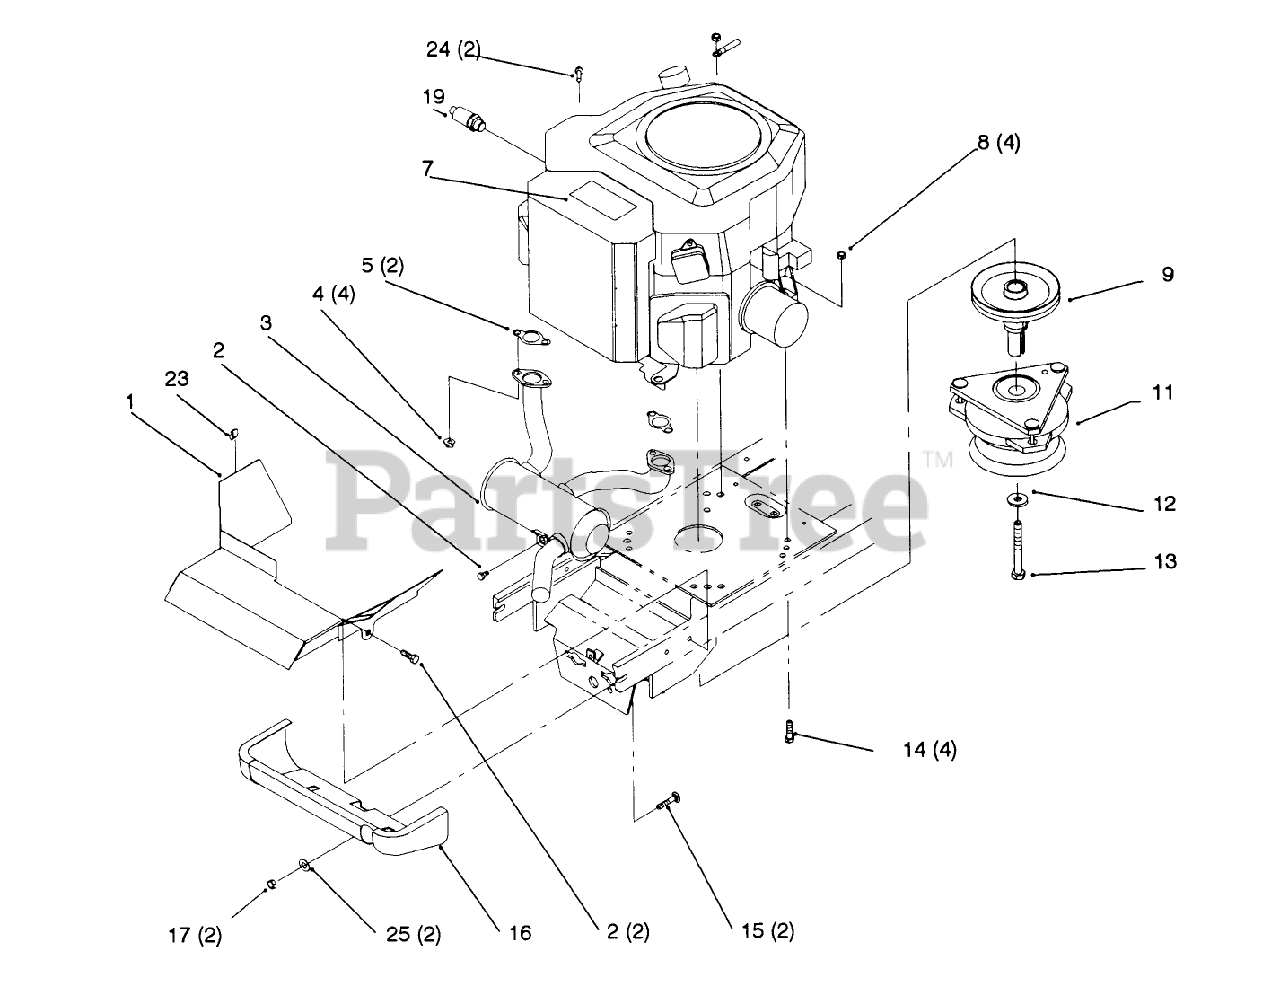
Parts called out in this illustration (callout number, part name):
2	SCREW
7	DECAL - ENGINE
8	NUT-LOCK, NI
9	PULLEY-ENGINE
11	CLUTCH - ELEC PTO
12	WASHER
13	SCREW-HH
14	SCREW-HH
15	SCREW-CARR
17	NUT-LOCK, NI
19	VALVE-DRAIN, OIL
23	CLIP-RETAINER, WIRE
24	SCREW-PPH
25	WASHER-FLAT
